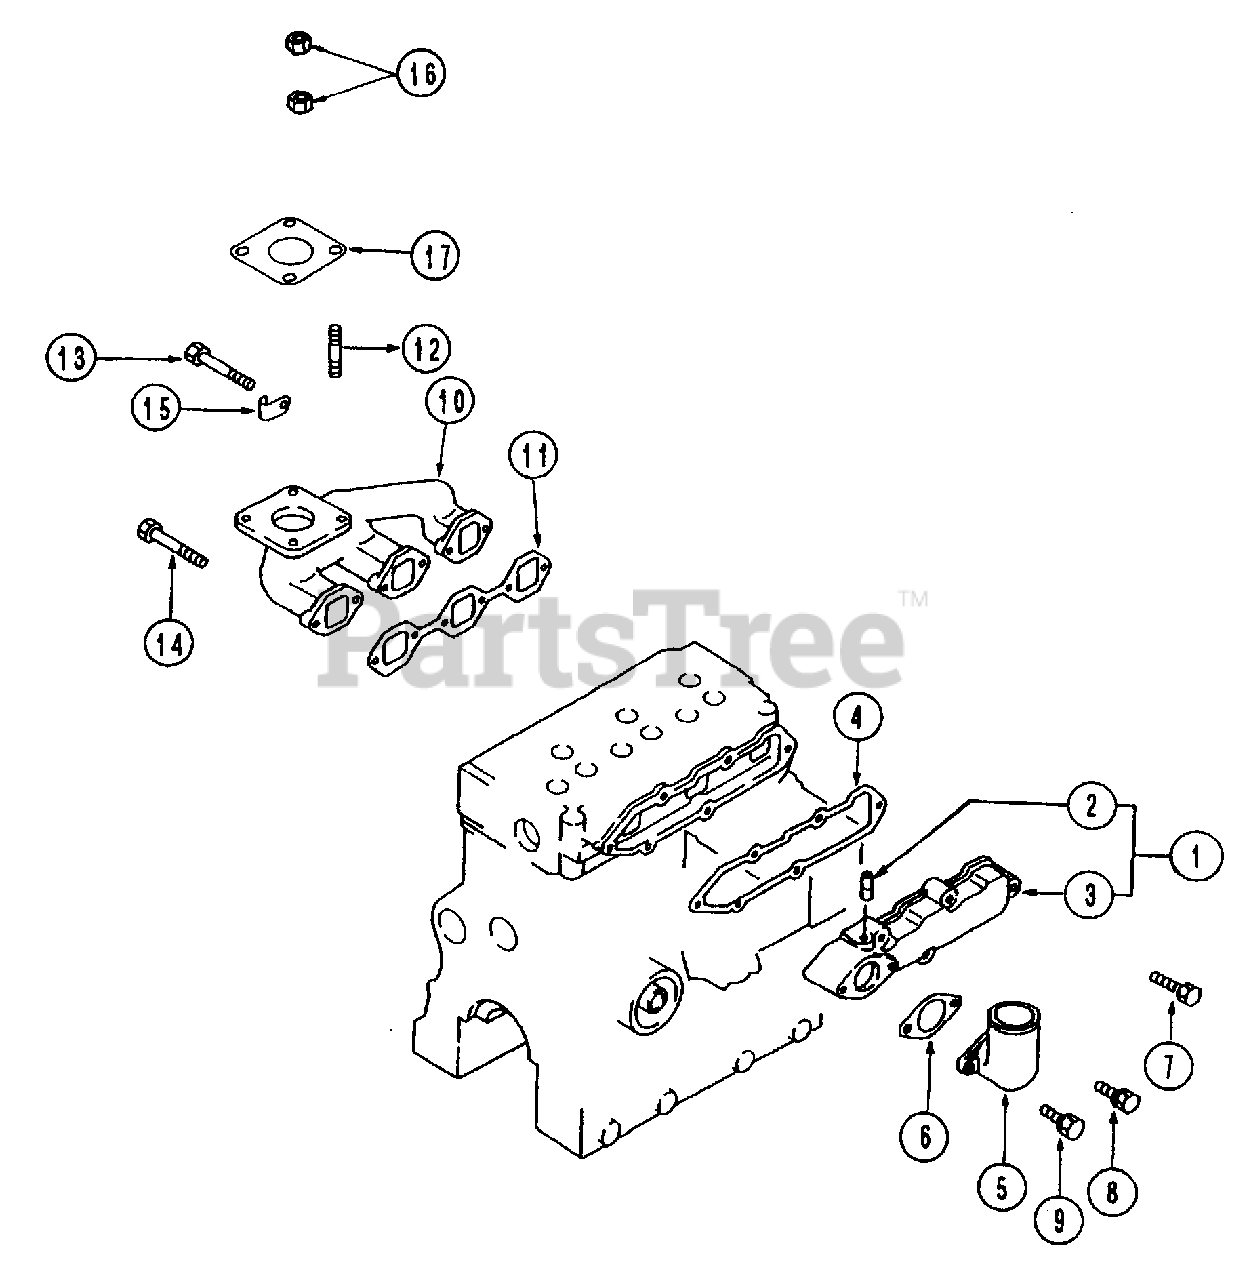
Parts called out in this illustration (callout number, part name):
1	Cover Ass'y., Inlet
2	Pipe
3	Cover Inlet
4	Gasket, Inlet
6	Gasket, Inlet
7	Bolt, W/Washer
8	Bolt, W/Washer
9	Bolt, W/Washer
10	Manifold, Exhaust
11	Gasket, Exhaust
12	Stud
